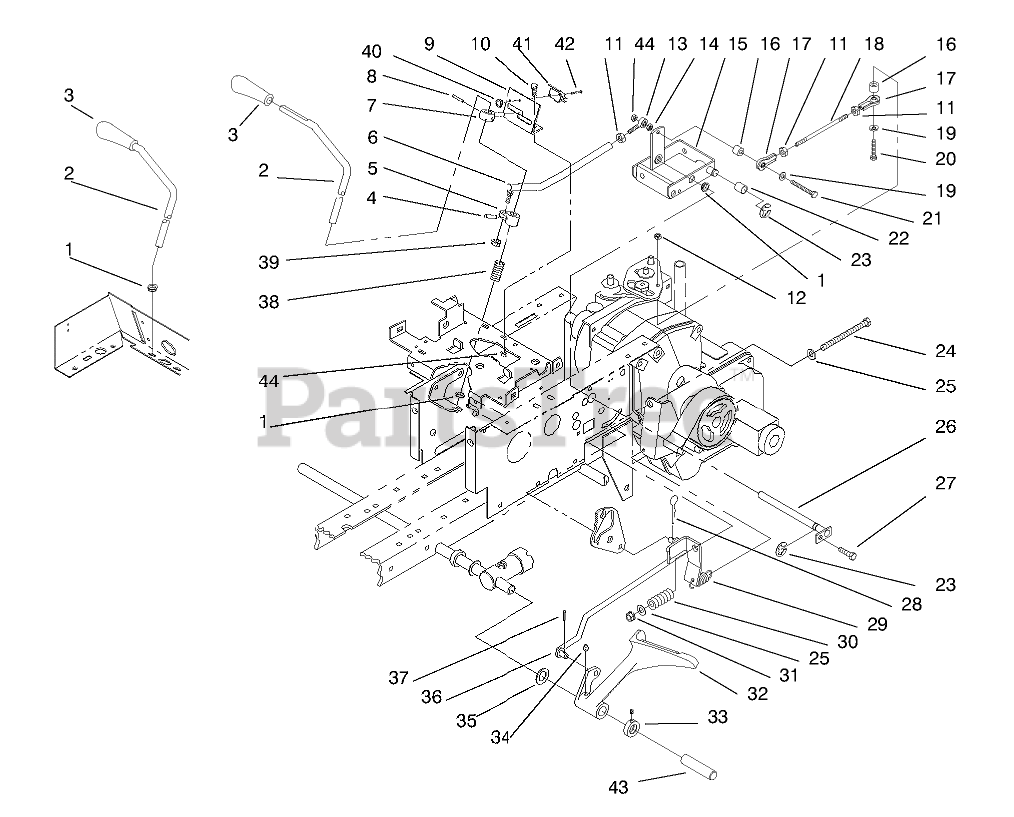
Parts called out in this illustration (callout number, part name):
1	NYLINER BUSHING
2	ROD-MOTION CONTROL
3	KNOB, MOTION CONTROL
4	SPIROL PIN 7/32X7/8
5	ARM-CONTROL
6	ASSY-ROD & BALL JOINT
7	GUIDE-CONTROL
8	PIN-SPECIAL
9	BRKT-CONTROL (BLACK)
10	SCREW-HH
11	NUT-JAM
12	NUT-LOCK, NI
13	ROD END, 1/4-28
14	NUT-HEX
15	ASY-CAM CNTROL (BLACK)
16	Spacer
17	ASSY ROD END
18	ROD-CONTROL
19	WASHER-FLAT
20	SCREW-HH
21	HHCS 1/4X2.25 FULL T
22	BEARING-CAM RETURN
23	RING-RETAINING, EXTERNAL
24	SCREW-HH
25	WASHER-FLAT
26	ASSY-ROD CAM PIVOT
27	Bolt
28	PIN-HAIR
29	SPRING
30	SPRING-COMPRESSION
31	NUT-LOCK, NI
32	PEDAL-BRAKE, HYDRO (RED)
33	COLLAR
33:1	SCREW-HSH
34	FITTING-GREASE
35	WASHER
36	Rod-Brake
37	PIN-COTTER
38	SPRING-COMPRESSION
39	NUT-LOCK
40	NUT-HEX
41	SWITCH - CLUTCH
42	SCREW-PPH
43	SLEEVE-PROTECTIVE
44	NUT-HEX
